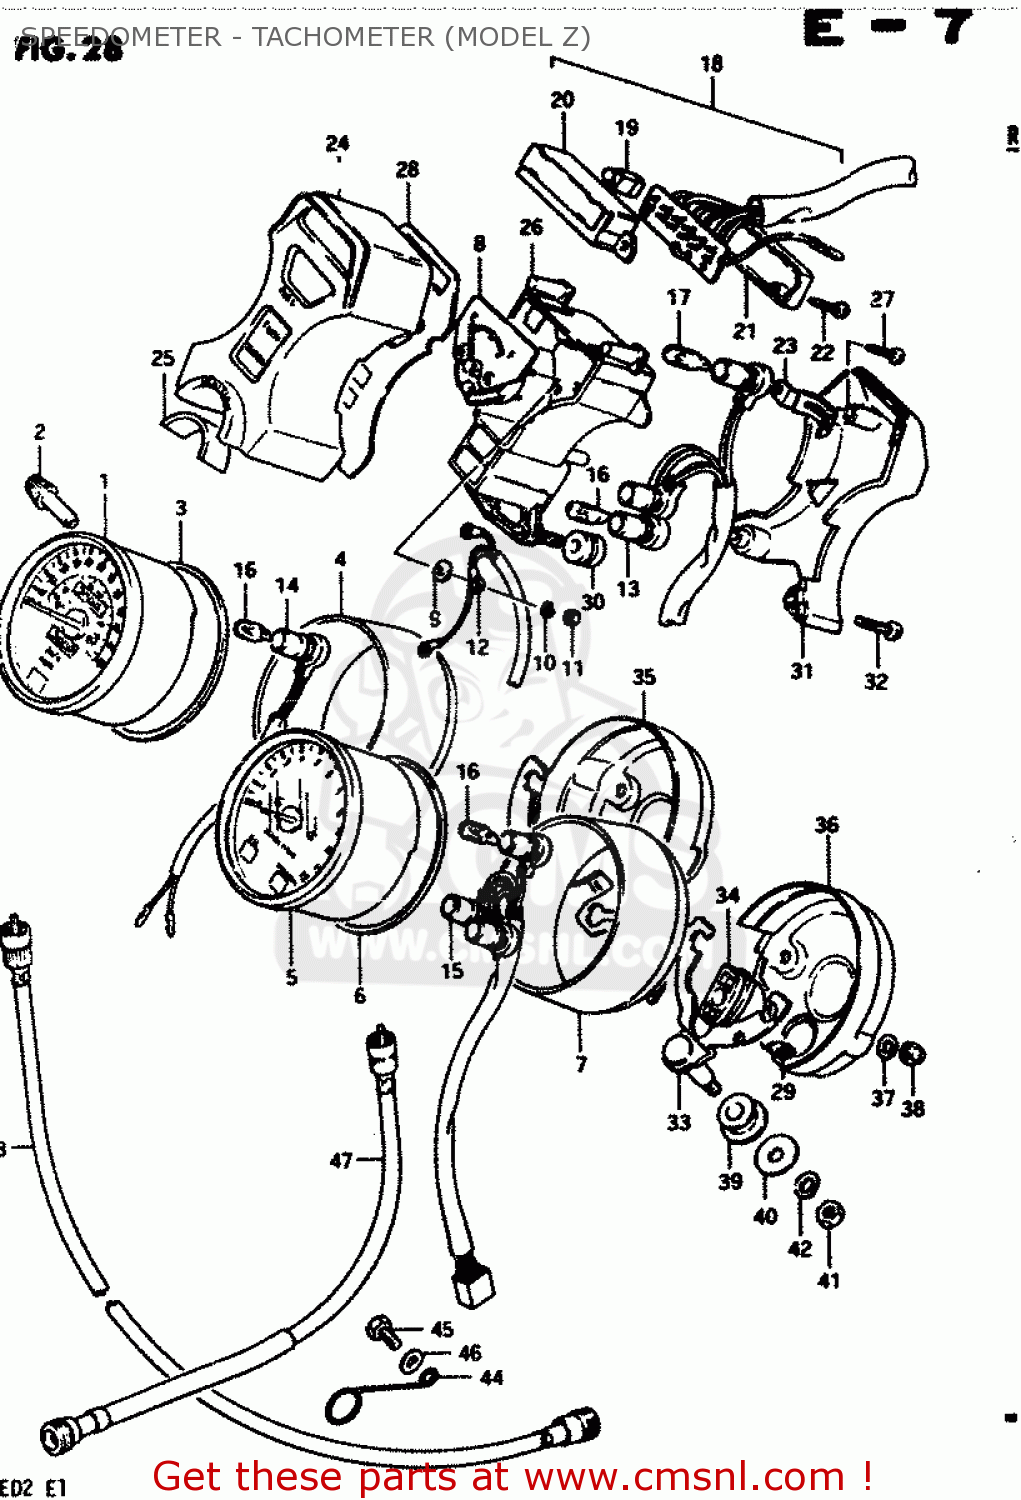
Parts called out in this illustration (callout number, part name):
1	SPEEDOMETER (KILO)
2	KNOB
3	CUSHION,SPEEDOMETER
4	COVER,SPEEDOMETER
5	TACHOMETER
6	CUSHION,SPEEDOMETER
7	COVER,TACHOMETER
8	METER,FUEL
9	WASHER,FUEL METER
10	LOCK WASHER
11	NUT 3MM
12	LEAD WIRE, FUELMETER
13	SOCKET,PILOT CASE
14	SOCKET,METER
15	SOCKET,TACHOMETER
16	BULB(12V3.4W,T10)
17	BULB(12V1.7W,T10,WB121)
18	INDICATOR ASSEMBLY,GEAR POSITION
19	BULB(14V1.12W)
20	CASE,GEAR INDICATOR
21	COVER,LWR
22	SCREW,GEAR INDICATOR
23	CLAMP,CORD
24	CASE,PILOT BOX
25	SEAL,IGNITION SWITCH
26	CASE,PILOT BOX,INNER
27	SCREW,INDICATOR
28	PLATE,PILOT BOX
29	CUSHION
30	CUSHION,PILOT BOX
31	COVER,PILOT BOX,UNDER
32	SCREW
33	BRACKET,COMBINATION METER
34	CUSHION,METER
35	COVER,METER,UNDER
36	COVER,TACHOMETER
37	WASHER
38	NUT
39	CUSHION,METER BRACKET
40	WASHER (8.5X29X1.6)
41	NUT
42	LOCK WASHER
43	CABLE ASSY,SPEEDOMETER
44	CLAMP,SPEEDOMETER CABLE
45	BOLT
46	WASHER
47	CABLE ASSEMBLY,TACHOMETER
